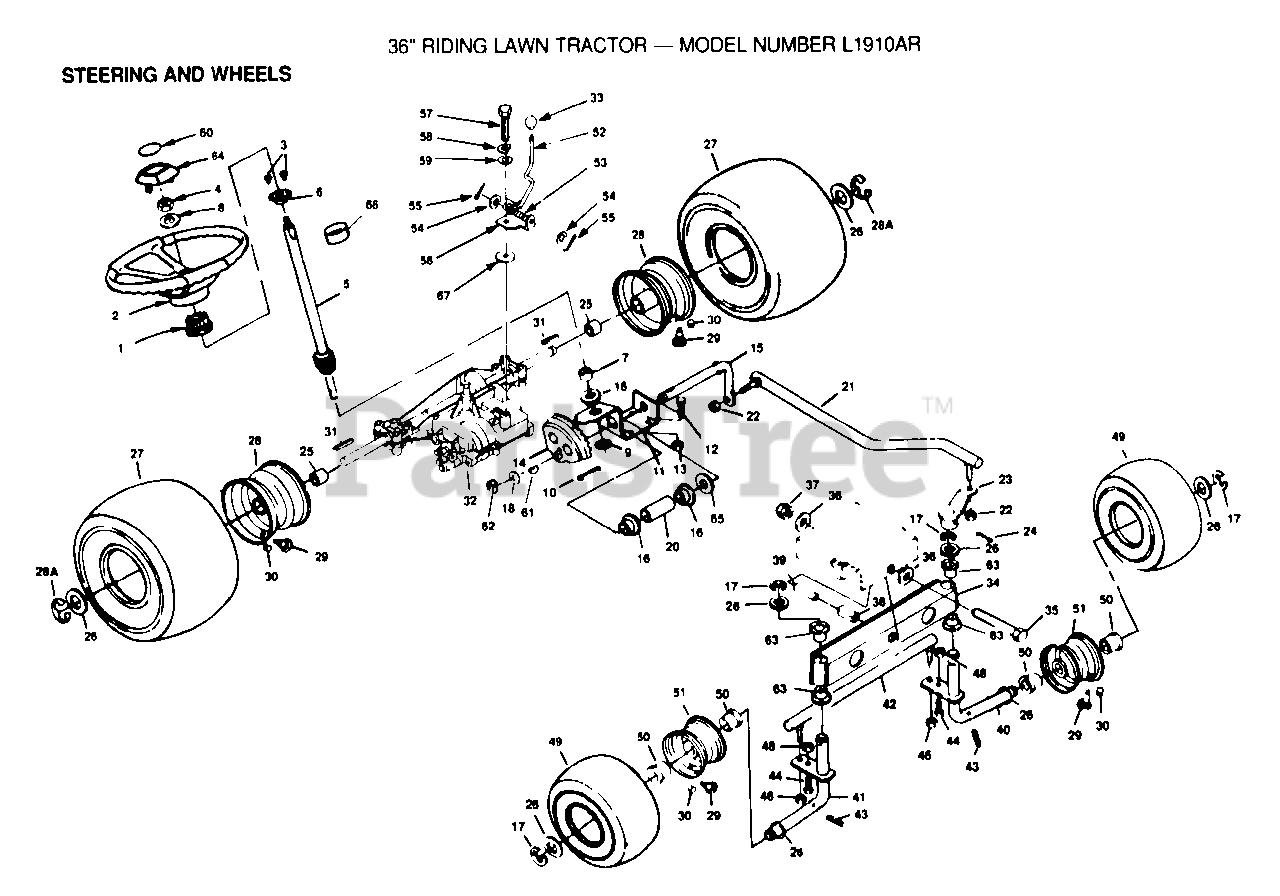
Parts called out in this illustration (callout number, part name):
1	ADAPTER LT
5	STEERING SHFT LT
7	SHAFT SPACER LT
8	WASHER
9	WASHER
11	STEERING BRKT T
12	BOLT
14	GEAR LT
15	STEERING ROD LT
16	BUSHING
17	RING
18	WASHER
22	GRIPCO NUT
23	STEERING ARM T
25	SPACER LT
26	WASHER
28A	E-RING LT
29	VALVE STEM LT
30	VALVE CAP
32	TRANSAXLE ASSY
33	CONTROL KNOB LT
36	WASHER
37	NUT LTV
38	ROCKER PIVOT LT
39	PIVOT SPACER LT
40	KINGPIN ASSY LH
46	NUT.LOCK.5/16-24
50	"LT, BEARING"
51	RIM ASSY LT
53	SPRING LT
54	WASHER
55	PIN COTTER 1/8
56	SHIFT PLATE LT
58	LOCKWASHER
59	WASHER LT
62	KLIP RING
63	COL. SRTG. BEAR.
64	INSERT-WHEEL LT
65	WASHER LT
